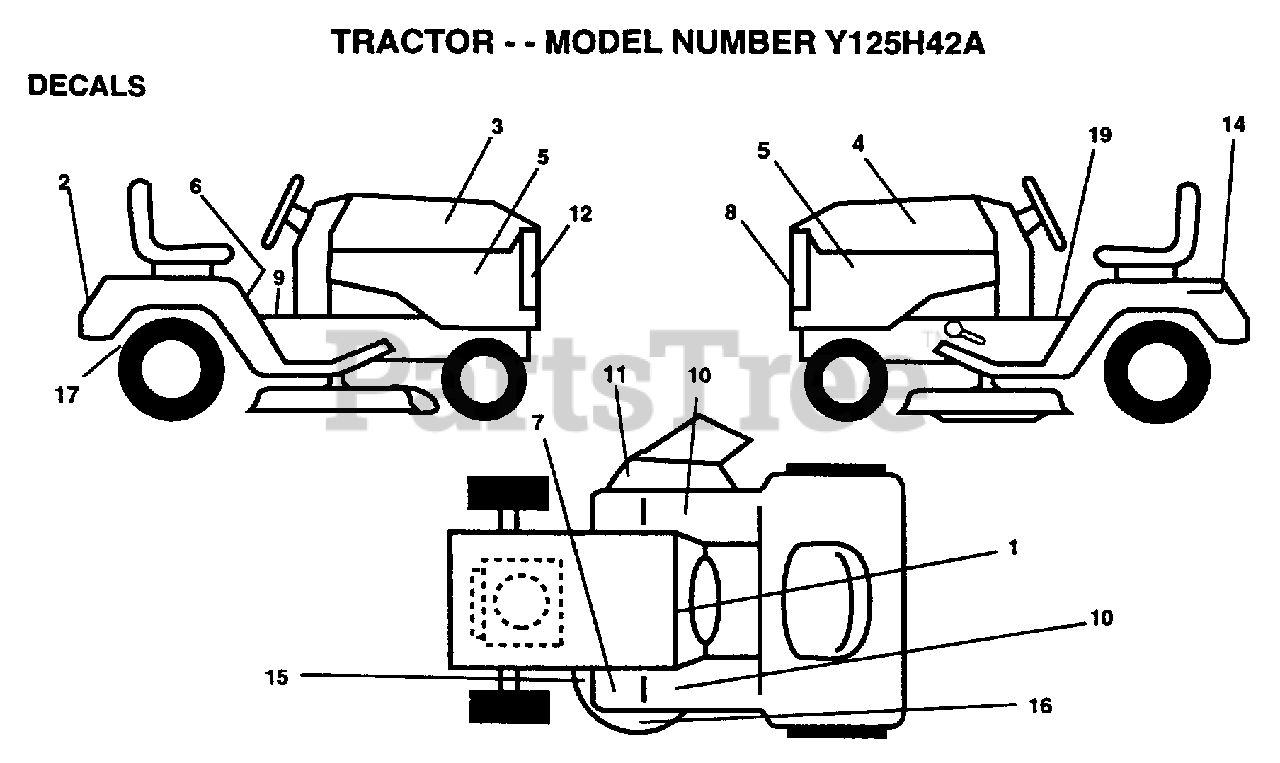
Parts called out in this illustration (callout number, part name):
1	DECAL.DASH.INSTR.
5	DECAL.PANEL.SIDE
6	DECAL CAUTION
7	DECAL T
9	DECAL SADL HYDRO
10	FOOTREST PAD
11	"DECAL, WARNING"
12	DECAL.GRILL.YARDP
14	DECAL
15	DECAL
17	DECAL DRAWBAR LH
19	DECAL BRAK PARK
